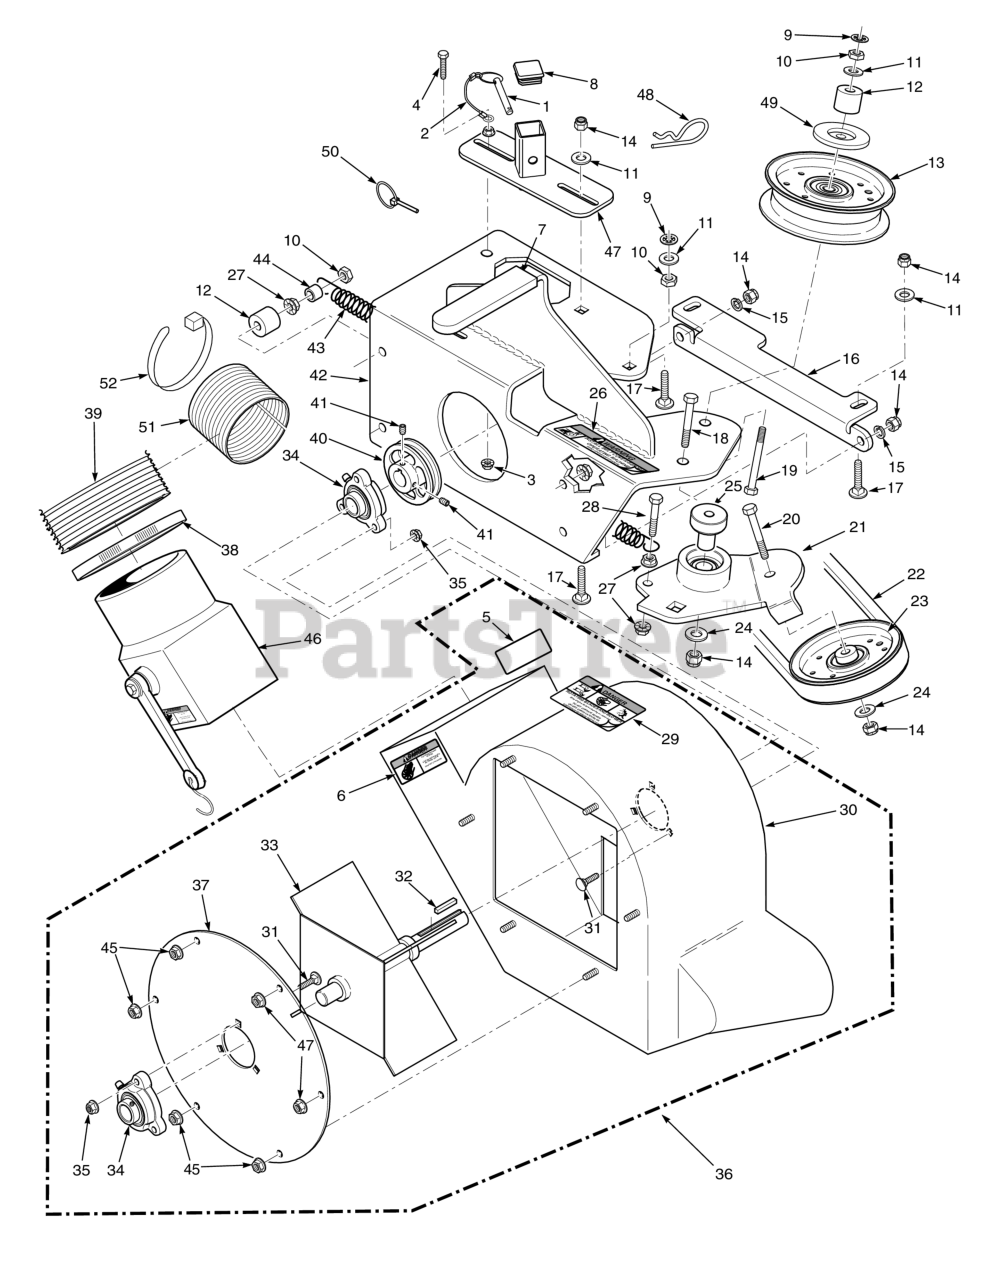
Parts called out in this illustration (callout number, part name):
1	Pin, Ring 1/2 x 2-1/4"
2	Lanyard, Deck Height Pin
3	NUT, 1/4-20 SERRATED FLANGE HEX HEAD
4	NUT, 1/4-20 SERRATED FLANGE HEX HEAD
5	Decal, Blower
6	Decal, Rotating Blower
7	Grip, Deck Latch Lever
8	Cap, Square Vinyl
9	Nut, Push-On - 3/8" Dia.
10	Bolt, Hex Head 3/8-16 x 1" Ser. Flg.
11	Flatwasher, 3/8" Special (.391 x .938 x .105)
12	SPACER, J-PULL ROD
13	Pulley, Idler 3-1/2" Dia. - 52"
14	HEX NUT, ELASTIC STOP LOCK, 3/8-16
15	Lockwasher, 3/8" Spring, Kawasaki FX / FT & FT-EFI / B&S 32BV
16	Plate, Catcher Mounting
17	Bolt, RDHD Carr. 3/8-16 x 1-1/2 (52" & 61")
18	Bolt, Hex Head 3/8-16 x 3" - 52"
19	Bolt, Hex Head 3/8-16 x 3-1/2" Full Thread
20	Bolt, Hex Head 3/8-16 x 1-3/4" (Kohler EFI)
21	Idler Arm Assembly - 52"
22	Belt, GC-SCZ-48V / STCII-48V
23	Pulley, 3-1/2" O.D., GC-STT 52"
24	Flatwasher, 3/8 (.391 x .938 x .105 HD) Grade 8
25	Pivot, Idler - Short
26	Decal, Warning - Belt Cover
27	NUT, 3/8-16 SERRATED FLANGE HEX HEAD
28	Bolt, Hex Head 3/8-16 x 1-1/2" Grade 8 Black
29	Decal, Danger
30	Blower Housing Weldment w/Decals
31	Bolt, 5/16-18 x .75 RHSN Carriage
32	KEY 1/4 X 1/4 X 1 1/2"(FOR 1" CRANKSHAFT
33	Fan Weldment
34	Bearing Assembly
35	HEX NUT, ELASTIC STOP LOCK, 5/16-18
36	Blower Housing Assembly, GC-STT
37	COVER, BLOWER HOUSING
38	Clamp, 8-5/8" Max Dia. (61")
39	Hose, 8.00" Dia. x 53" Long
40	Pulley, 4-3/4" O.D. - 1" Bore
41	Setscrew, Hex Socket Knurl Cup Pt. 5/16 - 18 (nylock)
42	Frame, Blower Mount
43	Spring, Helper (61" Cutter Deck Only)
44	Spacer, Deck Assist
45	Nut, Serrated Flange 5/16-18 (Right Front Engine Mounting, Briggs and Kohler Only)
46	Adapter, Blower GC-STC,
47	Receiver Weldment, Mount Post - 61"
48	Hair Pin Cotter, .177" x 3-1/4"
49	Quick Pin, 5/16" Dia.
50	Quick Pin, 5/16" Dia.
51	Hose, 8" Dia. x 24" Split
52	Cable Tie, .345 X 31.5 Black
